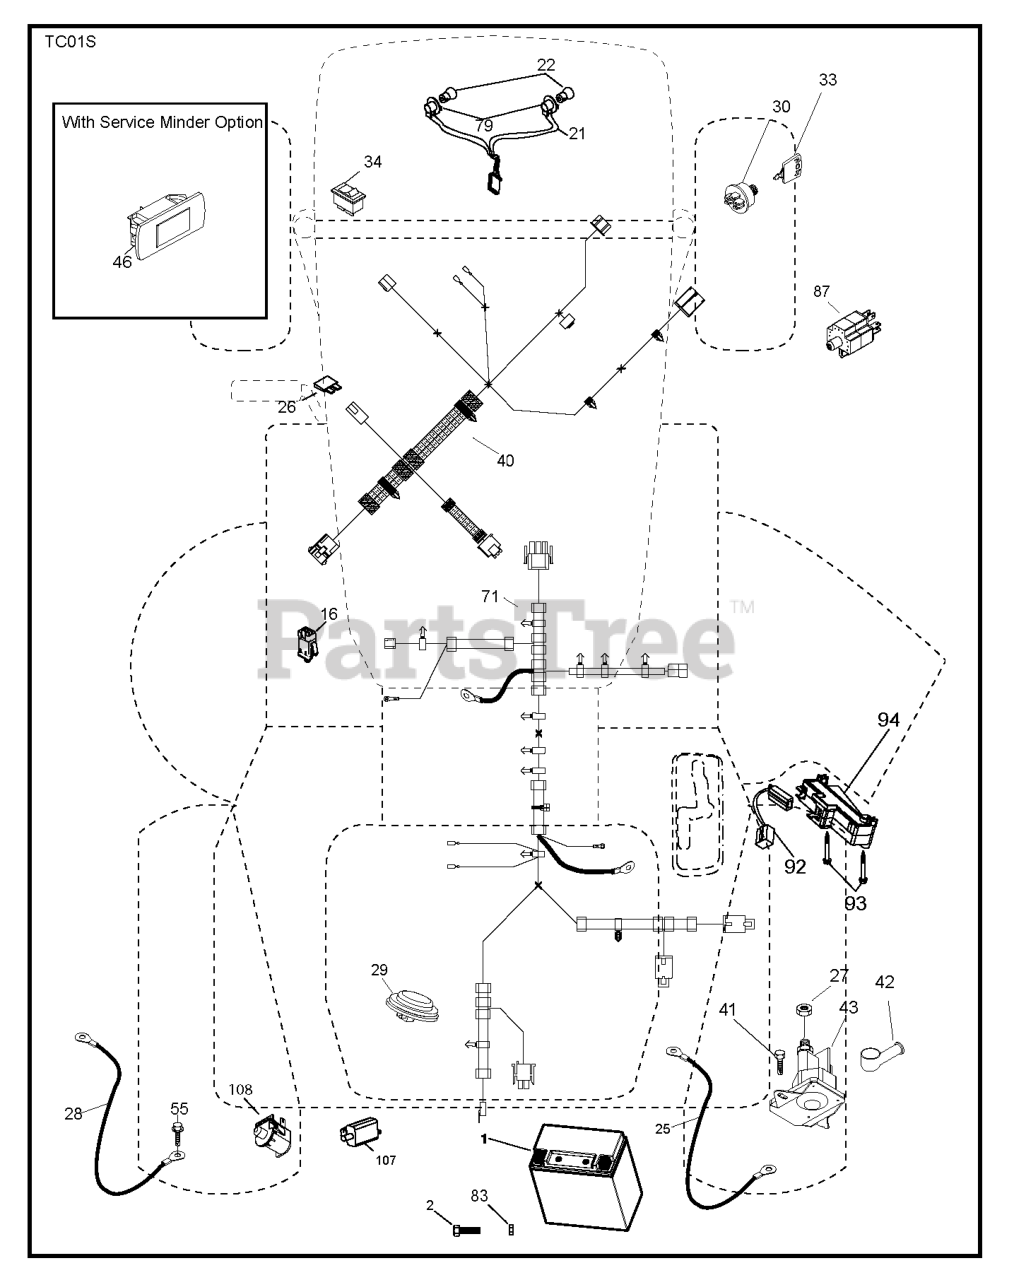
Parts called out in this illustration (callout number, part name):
1	BATTERY BATTERY 14AH 12V LEOC
2	SCREW.HEX.HEAD.CAP.M6 X1.12W
16	SWITCH INTERLOOK PUSH-IN
21	HARNESS.LIGHT W/4152J BULBS
25	RP.CABLE BATTERY CABLE
26	FUSE 20AMP
27	NUT
29	SWITCH.SEAT.DELTA.OPC.
30	SWITCH.IGN.DELTA.W.LGH.ROS
33	KEY.CHAIN.BLISTER.PACK.GEN.INT
40	RP HARNESS.ELECTRICAL.DASH.SRD
41	SCREW
42	TERMINAL COVER
43	SOLENOID.W/BRASS.PLUNGER
55	SCREW 5/16"
79	BULB HOLDER ASM.
83	NUT NUT SQUARE
87	RP SWITCH.RAILMOUNT.NO-NC-NC
92	HARNESS.PIGTAIL.CONSLE
93	SCREW.PLASTITE
94	MODULE.REVERSE.ROS
107	.WITCH.FULL BAGGER.INDICATOR
108	SWITCH.SNAPMOUNT.NC
